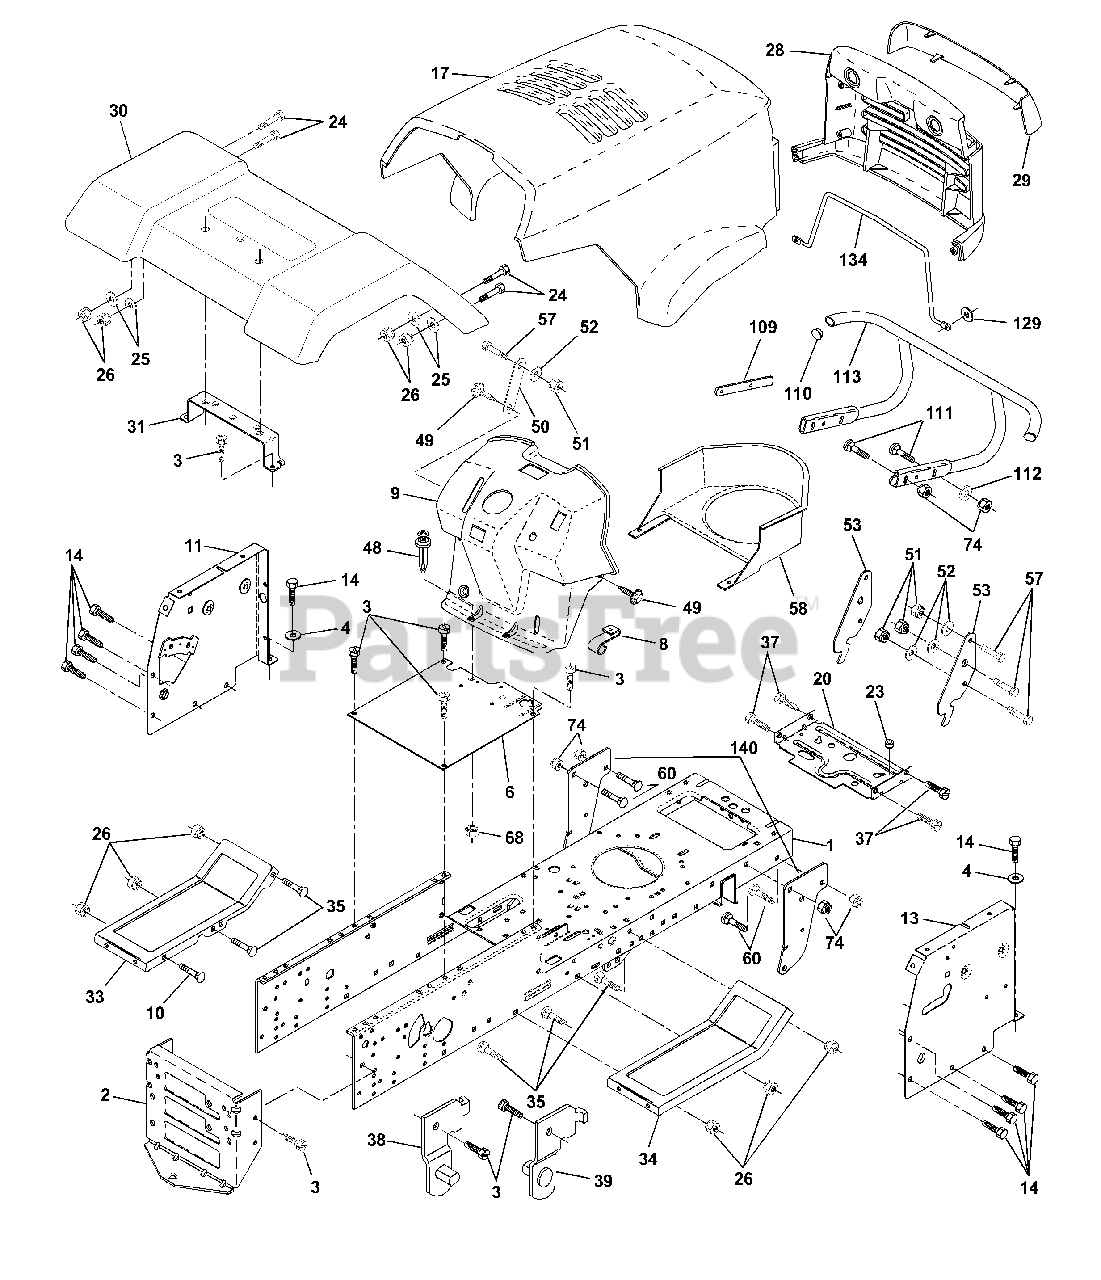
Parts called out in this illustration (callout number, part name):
1	Chassis Weldment 11ga
2	Drawbar, Stretch
3	Screw Thdrol 3/8-16x3/4 Ty-tt
4	Washer 13/32 x 3/4 x 16 Ga.
6	Saddle LT Fender Shift
8	Clip Insulator .406 Mtg Hole
9	Dash P/L N/Amm. N/HM w/PTO Grey
10	Bolt Carriage 3/8-16 x 1
11	Panel Pnt Dash Lh
13	Panel Dash Rh
14	Screw Thdrol 3/8-16x1/2 Ty-tt
17	Hood LT/PL Husqvarna
20	Plate Mtg. Battery Fuel Tank. 95
24	Bolt Fin Hex 3/8-16unc X 1 Gr. 5
25	Washer 13/32 X 13/16 X 12 Ga
26	Nut Lock Hex W/Ins 3/8-16 Unc
28	Grille LT/PL Husqvarna
29	Lens LT/PL Husqvarna
30	Fender Pnt
31	Bracket Pnt Fender
33	Footrest Pnt Lh
34	Footrest Pnt Rh
35	Bolt Rdhd Sht Sqnk 3/8-16 X3/4
37	Screw Thdrol 5/16-18 X 1/2
38	Bracket, Asm. Pivot, L.H., Mower Rear
39	Bracket, Asm. Pivot, R.H., Mower Rear
48	Rivet Push Plate D Plastick Blk
49	Screw Hexwsh. Thdrol 1/4-20 x 3/4
51	Nut Lock Hex W/Ins 1/4-20
52	Washer 9/32 x 7/8 x 16 Ga.
53	Bracket Pnt. Pick off LT/PL Husq.
57	Bolt Hex 1/4-20 x 3/4
58	Air Duct P/L
60	Bolt Rdhd Sqnk 3/8-16 Unc x 3/4
68	Nut Keps Hex 1/4-20
74	Nut Crownlock 3/8-16 UNC
109	Bracket Extension Bumper
110	Plug Plastic
111	Bolt Carriage 3/8-16 x 1-1/4
112	Washer 13/32 x 13/16 x 16 Ga.
113	Bumper Asm.
129	Washer 9/32 x 5/8 x 16 Ga.
134	Rod Support Hood LT/PL Husq.
140	Bracket Chassis Front 7 Ga.
